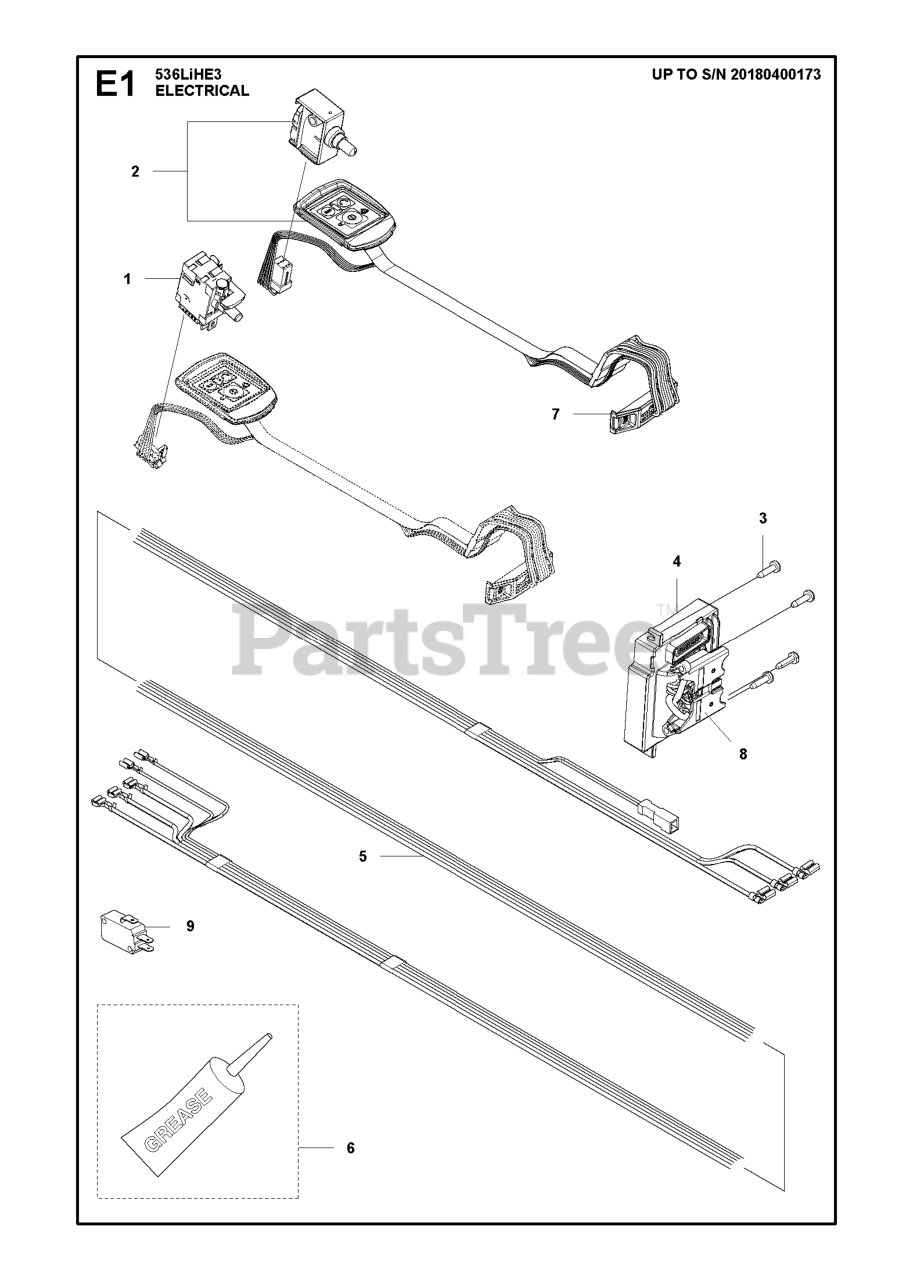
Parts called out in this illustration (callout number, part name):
1	TRIGGER SWITCH
2	SWITCH KIT BATTERY POLE HEDGER
3	SCREW CITXPANT
4	CONTROL UNIT BLDC - 536LIHE3
5	WIRING ASSY POLE HEDGE MOTOR B
6	GREASE TUBE Q8 RUYSDAEL WR2
8	CONNECTOR BATTERY
